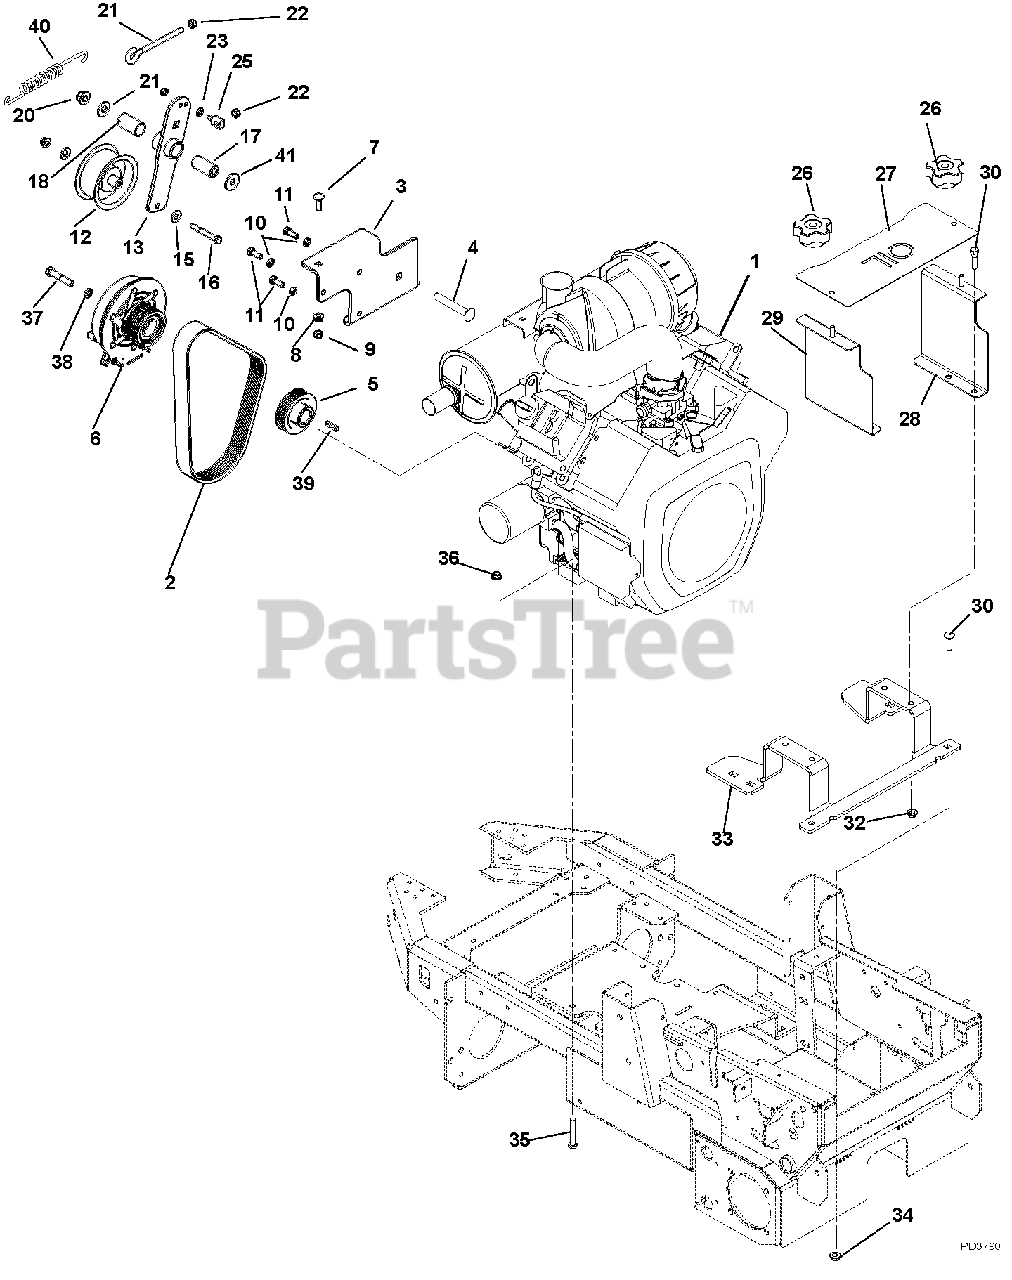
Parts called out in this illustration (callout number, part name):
1	Engine, 30 HP Kohler
2	Belt, 8 Rib Poly V L-Section
3	Bracket, PTO Idler Mounting
4	Bolt, Round Head Square Neck .50-13 x 3.50 Grade 5
5	Sheave, Poly-V
6	Clutch, 8 Groove Poly V L-Section
7	Bolt, Round Head Square Neck .38-16 x 1.25 Grade 5
8	Nut, .38-16 Nyloc Flange
9	Nut, Locking Center .38-16
10	Washer, Locking .38 x .094 Regular
11	Bolt, Hex .38-16 x 1.00 Grade 5
12	V-Idler, 4.00 x .38 (2.00 wide)
13	Assembly, Idler Pivot Assembly (includes items 14 and 18
14	Weldment, PTO Idler Pivot Arm (included in item 14)
15	Washer, Flat Steel .438 x 1.00 x .083
16	Bolt, Hex .38-16 x 2.75 Grade 5
17	Bushing, Spacer.505/.500 x .999/.996 x 2
18	Bushing, 1.00 x 1.125 x 1.936 (included in item 14)
19	Washer, Flat Steel .531 x 1.250 x .100
20	Nut, .50-13 Nyloc Flange
21	Bolt, Eye .38-16 x 4.50, .75" Eye
22	Nut, Hex .38-16
23	Washer, Flat Steel .344 x .688 x .065
24	Nut, Locking Center .31-18
25	Pin, Pivot
26	Knob, Clamping .312-18 Nyloc
27	Shroud, Cooling
28	Bracket, Tank Shroud Left Hand
29	Bracket, Tank Shroud Right Hand
30	Bolt, Hex .38-16 x 1.50 Grade 5
31	Bolt, Round Head Square Neck .38-16 x 1.00 Grade 5
32	Nut, .38-16 Nyloc Flange
33	Mount, Hydraulic Tank
34	Nut, .38-16 Nyloc Flange
35	Bolt, Hex .38-16 x 2.25 Grade 5
36	Nut, Locking Top Flange .38-16
37	Bolt, Hex .44-20 x 2.25 Grade 5 EP80
38	Washer, Locking .44 x .109 Regular
40	Spring, Tension .135 X.69 X 5.75
41	Washer, Flat Steel .511 x 1.44 x .125
